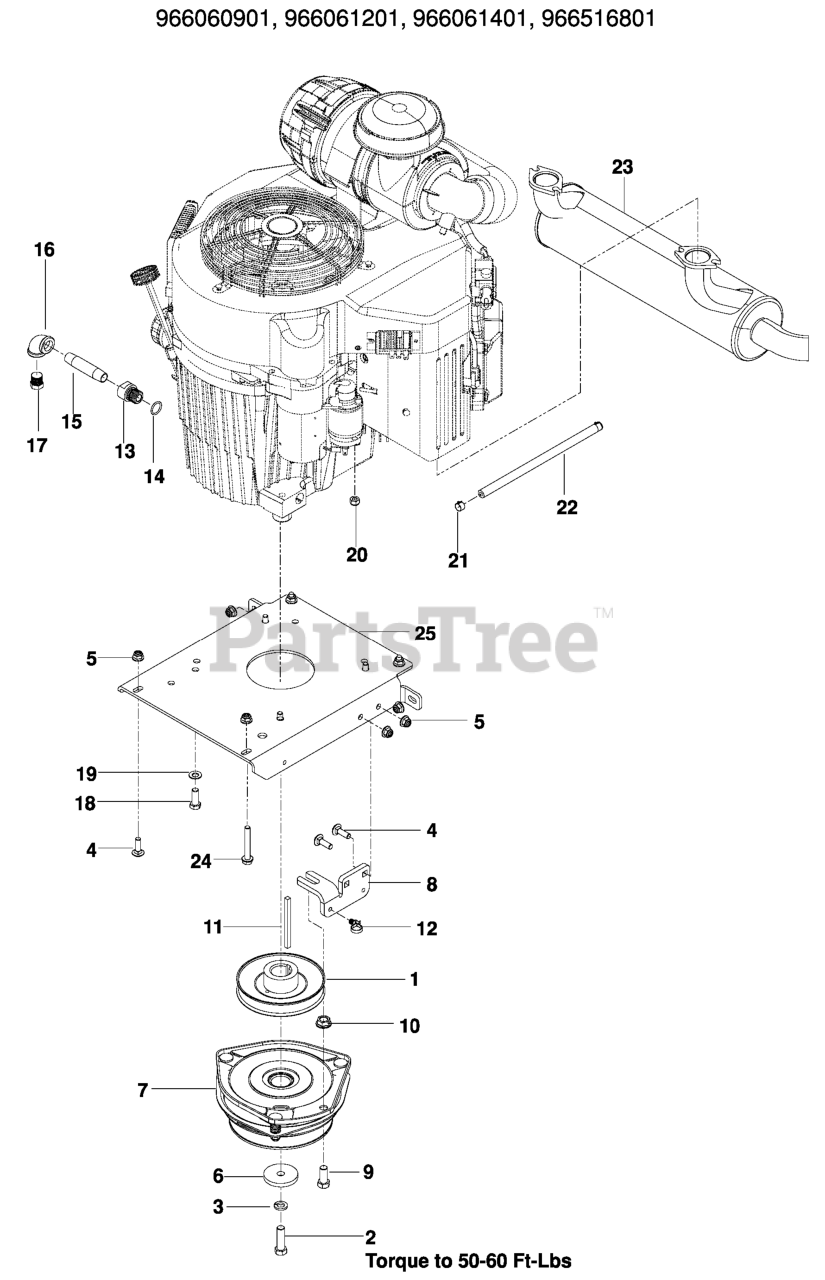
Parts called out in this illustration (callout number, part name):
1	PULLEY, ENGINE
2	HCS 7/16F X 1 1/2
3	WASHER 7/16 LOCK
4	RHSNB 5/16C X 1
5	5/16-18 NYLOC FLANGE NUT
6	BLADE WASHER
7	CLUTCH, GT3.5
8	STOP, CLUTCH, OGURA
9	HCS 7/16-14 X 1 GR 5 ZD
10	NUT 7/16C WHIZ
11	KEY, 1/4 SQ X 3.5
12	TIE WRAP, 8-3/8", W/CLIP
13	ADAPTER, OIL DRAIN
15	PIPE NIPPLE 3/8 X 3
16	90 DEG.ELBOW 3/8NPT
17	PLUG, DRAIN 3/8 NPTF
18	HCS 3/8-16X1.GRD.5.ZD
19	WASHER, 3/8 DISC SPRING SPEC
20	NUT M8-1.25 TOP NYL GR10 ZD
21	HOSE CLAMP
22	FUEL LINE 5"
23	MUFFLER.26HP.KAW.FX651V-730V
24	HHFS 5/16-18 X 2.25 GD 5
25	PLATE.ENGINE.BLACK
